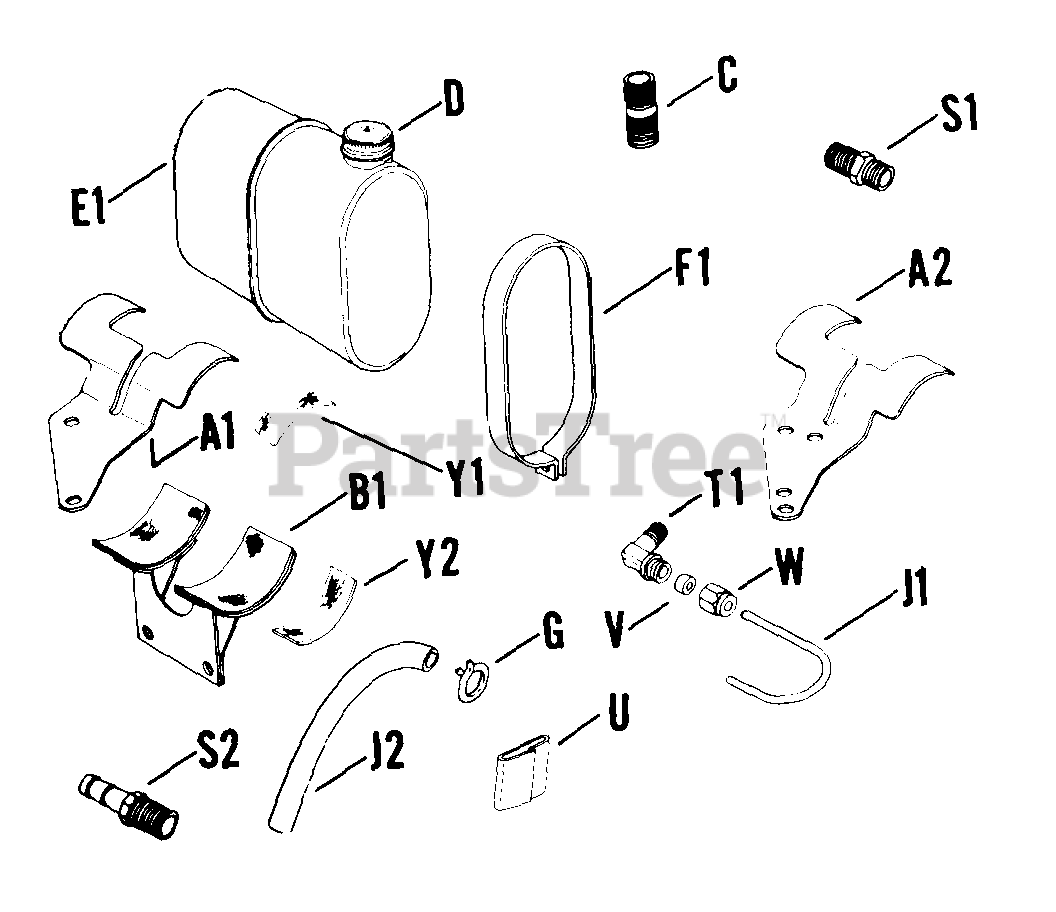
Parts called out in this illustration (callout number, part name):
B1	BRACKET - USE 47 217 11
C	PIPE - USE 47 136 02
E1	TANK, FUEL USE 47 065 10-S
F1	STRAP-DISCONTINUED
T1	ELBOW - (#DSC)
W	NUT - (#DSC)
